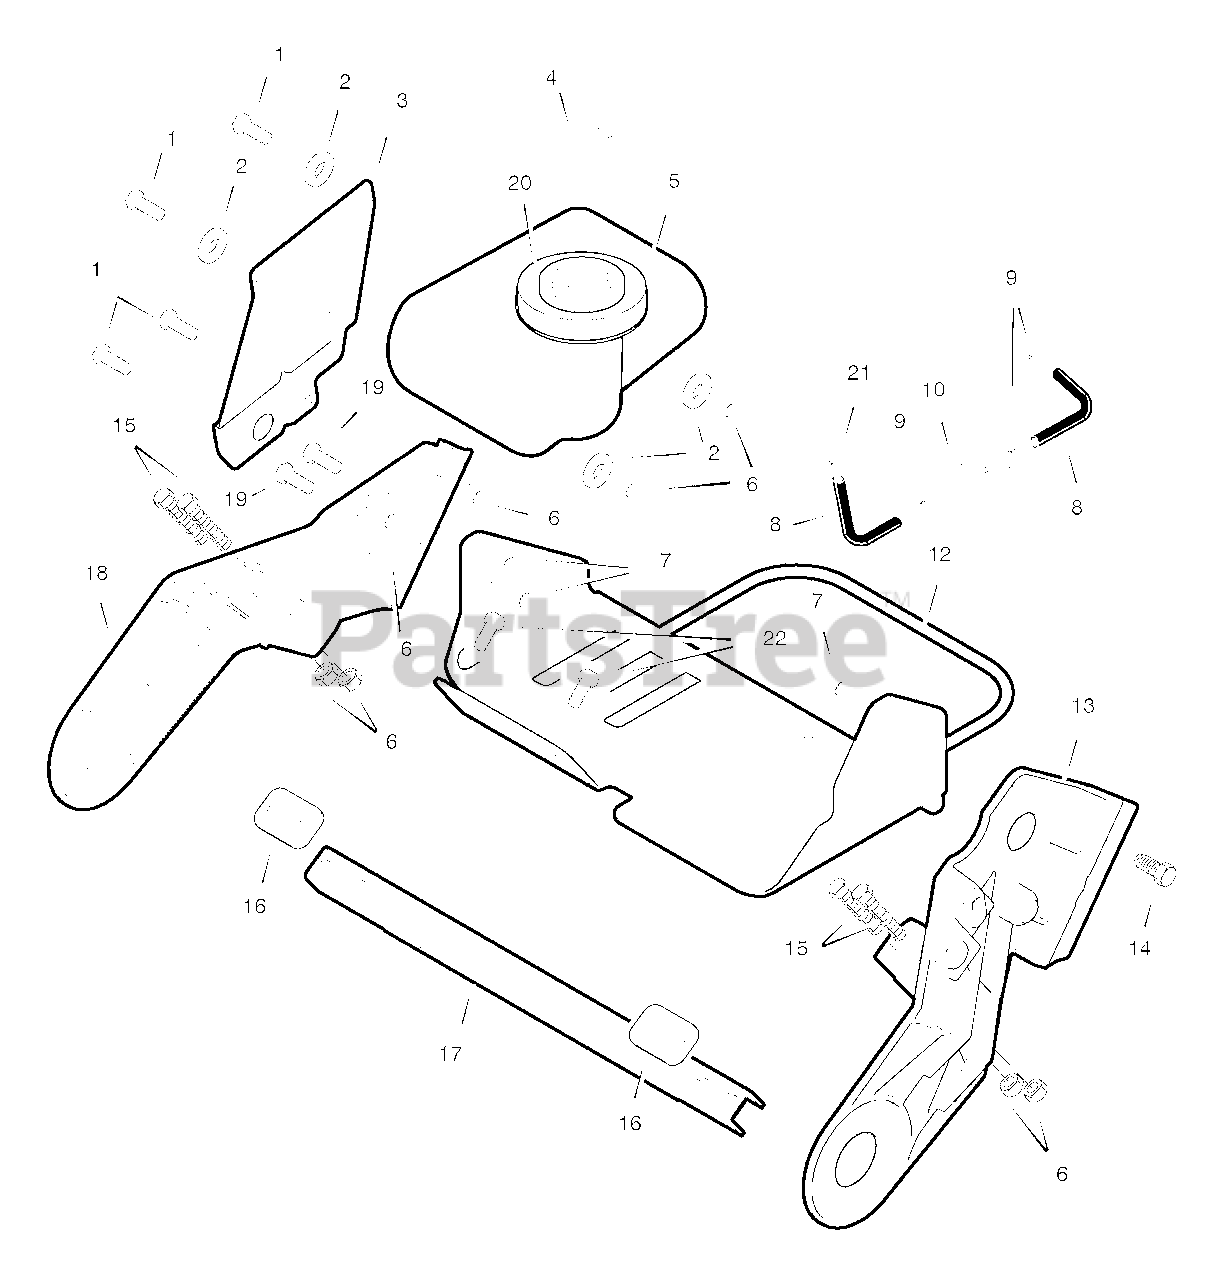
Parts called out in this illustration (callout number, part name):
1	Screw 1/4-20 x .75
2	Washer
3	Bracket, Fuel Tank
4	Cap, Fuel Tank
5	Tank, Fuel
6	Nut, Hex 1/4-20
7	Nut, Hex 5/16-18
8	HOSE, FUEL 12 INCHES
9	Clamp, Fuel Line
10	Filter, Fuel Line
12	Cradle Assembly, Engine
14	Screw, 5/16-18 x 0.63
15	Screw, 1/4-20 x 2.00
16	Plate, Mounting Support
17	Support, Frame
18	Frame, RH
19	Screw, 5/16-18 x 0.75
20	Ring, Foam
21	Clamp, Fuel Line -Screw Type
22	Screw, 1/4-20 x .625
